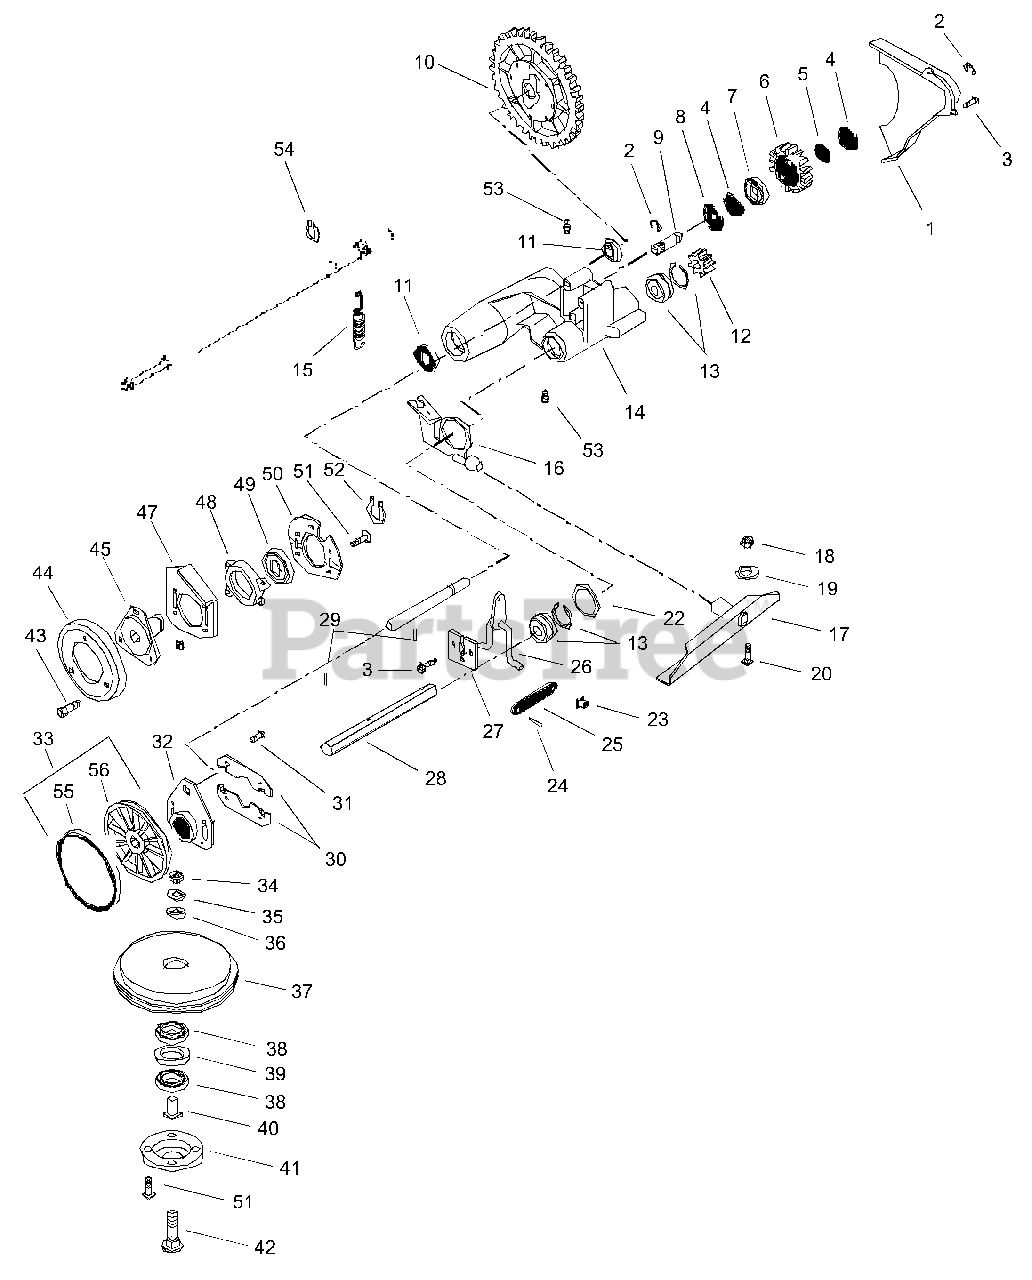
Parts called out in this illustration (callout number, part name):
1	GEAR COVER
2	RG-RTNG-EXT .438X.035
3	@SCR-TAP 12-24X.50 HWH TR YWZC
4	WSHR-FL-STL .52X.827X.062 YWZC
5	@WSHR-FL-STL.531X1.06X.095YWZC
6	IDLER GEAR
7	BRG-BALL .500X1.38X.437
8	RETAINER
9	IDLER SHAFT
10	DIFFERENTIAL ASSEMBLY
11	BRG-BALL .625X1.383X.50
13	BRG-BALL .562X1.375X.437
14	DRIVE MOUNT
15	SG-TENS .051X.60X2.25 WLD 7.0
16	DRIVE ACTUATOR WELDMENT
17	PIVOT CHANNEL WELDMENT
18	@NUT-LK-CTR .31-18 YWZC
19	@WSHR-FL-STL.344X.688X.065YWZC
20	@BLT-RHDSSQNK .31-18X.62 G5YZ
21	ROD - GUIDE
22	WSHR-FL-STL 1.390X2.00X.020 PL
23	PUSH NUT, .25
24	PIN-ROLL .125X.50
25	SHIFT LINK
26	SHIFT ARM WELDMENT
27	RETAINER PLATE
28	HEX SHAFT
29	PIN-ROLL .188X.88
30	THRUST PLATE
31	@SCR-TAP 10-24X.375 HWH YZ TR
32	GUIDE PLATE
33	FRICTION WHEEL ASSEMBLY
34	@NUT-HEX .31-18 YWZC
35	WSHR-LK .312X.097 HVY YWZC
36	WSHR-FL-STL .328X.875X.062YWZC
37	FRICTION SHEAVE
38	BRG-BALL .625X1.375X.43
39	WSHR-FL-STL 1.062X1.344X.032PL
40	SPINDLE - BEARING
41	RETAINER - BEARING
42	@BLT-RDHDSQNK .31-18X1.75 G5YZ
43	@BLT-HEX .25-20X.50 GR5 YWZC
44	FRICTION DISC
45	FRICTION WHEEL HUB
46	@NUT-LK-CTR .25-20 YWZC
47	BEARING PLATE
48	BEARING RETAINER
49	BRG-BALL 1.0X2.0X.56 (1641)
50	BEARING RETAINER
51	@SCR-TAP 12-24X.50 HWH TR YWZC
52	RG-RTNG-EXT 1.00X.042
53	FTG-LUBE .25-28X.256 YWZC
54	RG-RTNG-EXT .625X.035
55	FRICTION RING
56	FRICTION WHEEL HUB
